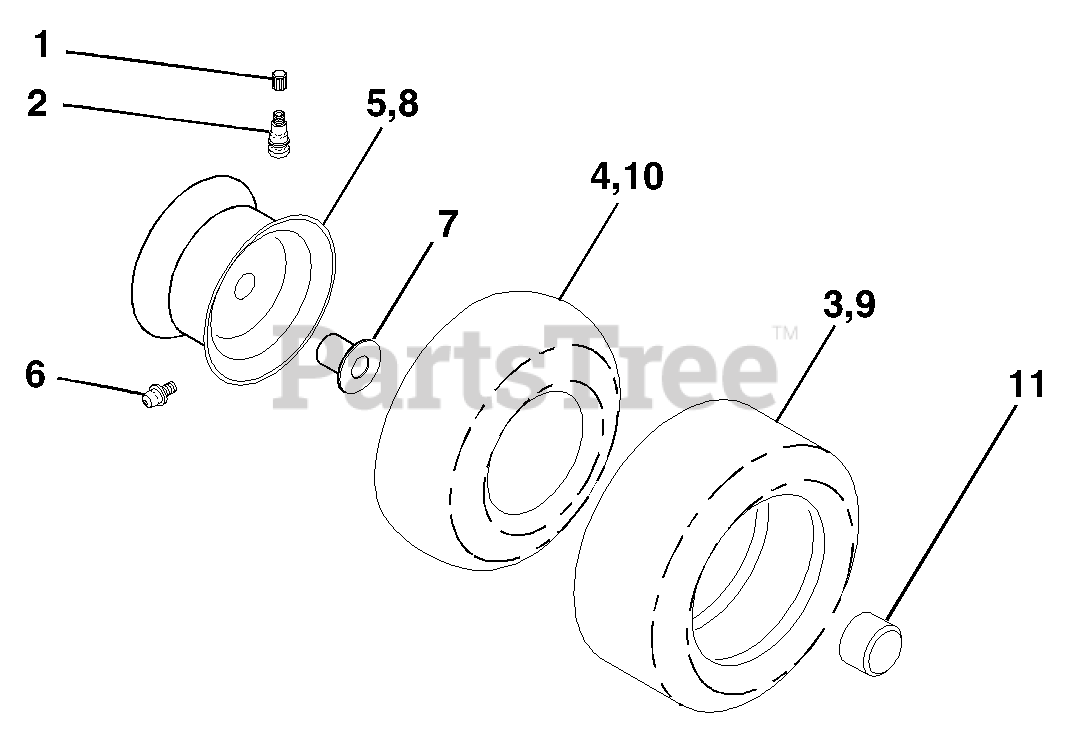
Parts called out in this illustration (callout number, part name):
1	Cap Value Tire
2	Stem Value
3	Tire F Ts 15 X 6 0 - 6 Service
4	Tube Inner Front #35060
5	Rim Asm 6"front White Service
6	Fitting Grease
7	Bearing Flange
8	Rim Asm 8"rear White Service
9	Tire R Ts 18 x 8.5-8 Service
10	Tube Rear 9 5 X 8 Service
11	Cap Axle Blk 1 50 X 1 00
